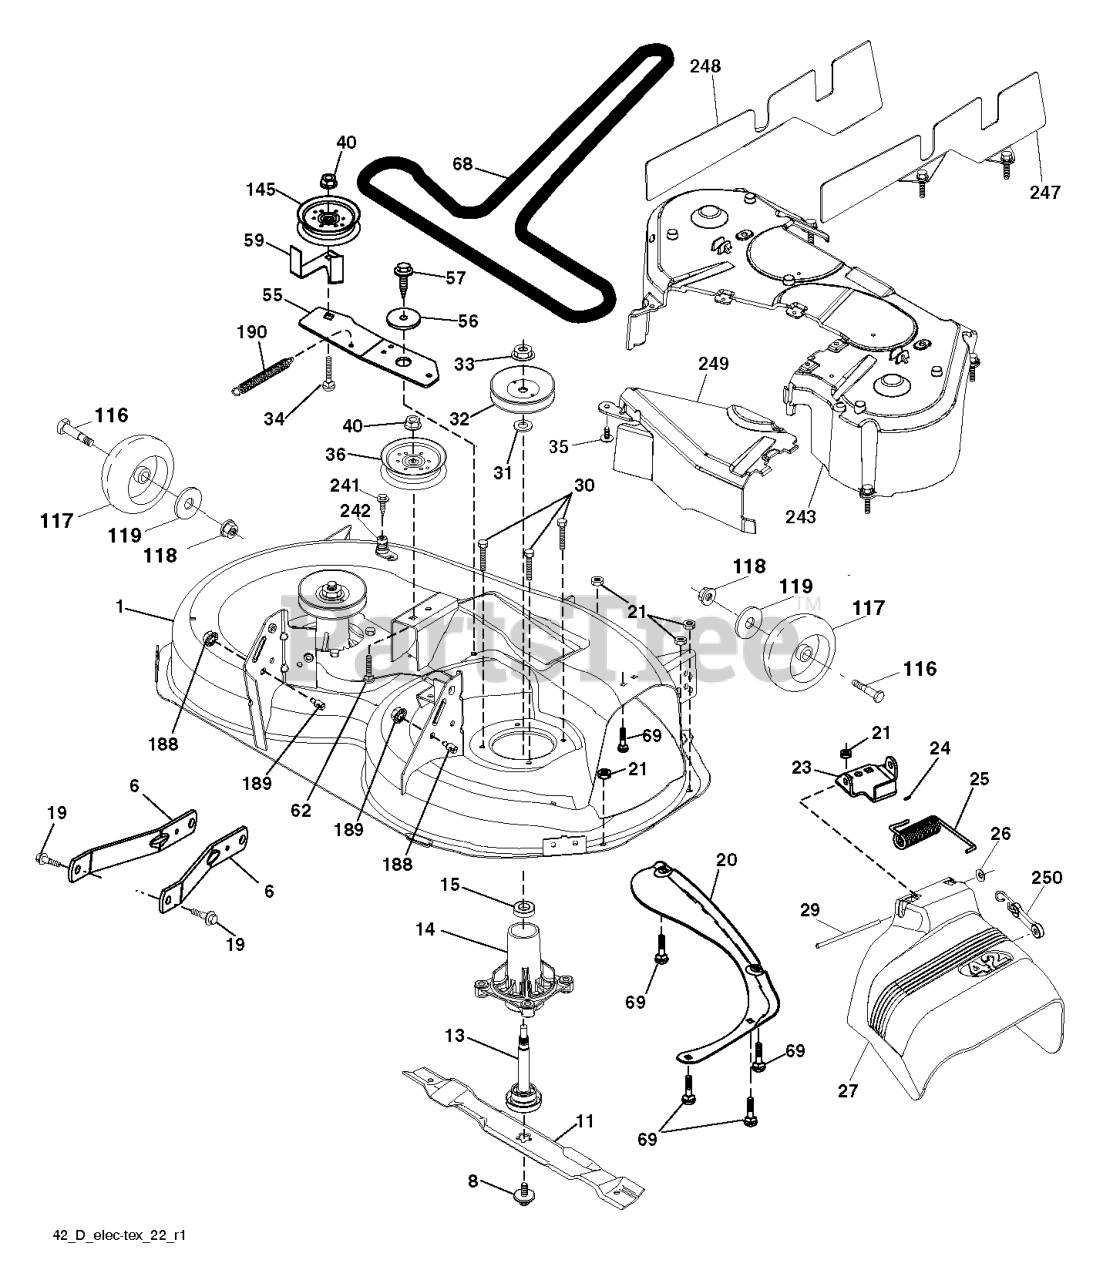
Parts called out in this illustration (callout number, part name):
1	DECK.WELDMENT.42"
6	ARM.SUSPENSION.MOWER.R
8	BOLT.WASHER.ASM.7/16-2
11	42" HI-LIFT BLADE
13	SHAFT.ASM.MDRL.N/GREASE.38
14	RP.HOUSING.MANDREL.4PT.
19	BOLT.SHOULDER
20	BAFFLE.VORTEX
21	LOCKNUT
23	BRKT.DEFLECTOR.38"2005+
24	CAP-SLEEVE LT
25	SPRING.TORSION.DEFLECT
26	NUT PUSH M
27	DEFLECTOR ASM.42"TEX.FRENCH
29	ROD.HINGE
30	SCREW, WASHER HEAD
31	WASHER.SPACER.MANDREL
32	PULLEY/MANDREL
33	NUT.FLANGE.LOCK.TOP
34	BOLT.3/8-16X1.50
35	FASTENER.XMAS.TREE
36	PULLEY.IDLER.2006
40	NUT LOCK FLG 3/8-16 UNC
55	IDLER.ARM.42"
56	SPACER.RETAINER
57	SCREW 3/8-16X1
59	GUARD, BELT
68	BELT V SECONDARY
69	BOLT
116	BOLT M
117	WHEEL.GAGE.HALF.SPOKED
118	NUT LOCK FLG 3/8-16 UNC
119	WASHER.5/16.FLAT.STE.STD.
145	PULLEY.IDLER.48"PRIMARY
188	STUD.FASTNER.W/ANTI-ROTATE
189	NUT LOCK HEX FLANGE 5/16-18
190	SPRING.MOWER.DRIVE.ELECTRIC
241	SCREW.TT.#10-32X.5.3/8.FLANGE
242	PORT.WASHOUT
243	COVER DECK
247	SHIELD RIGHT
248	SHIELD LEFT
249	COVER CABLE CLUTCH
250	ELASTIC STRAP KIT
